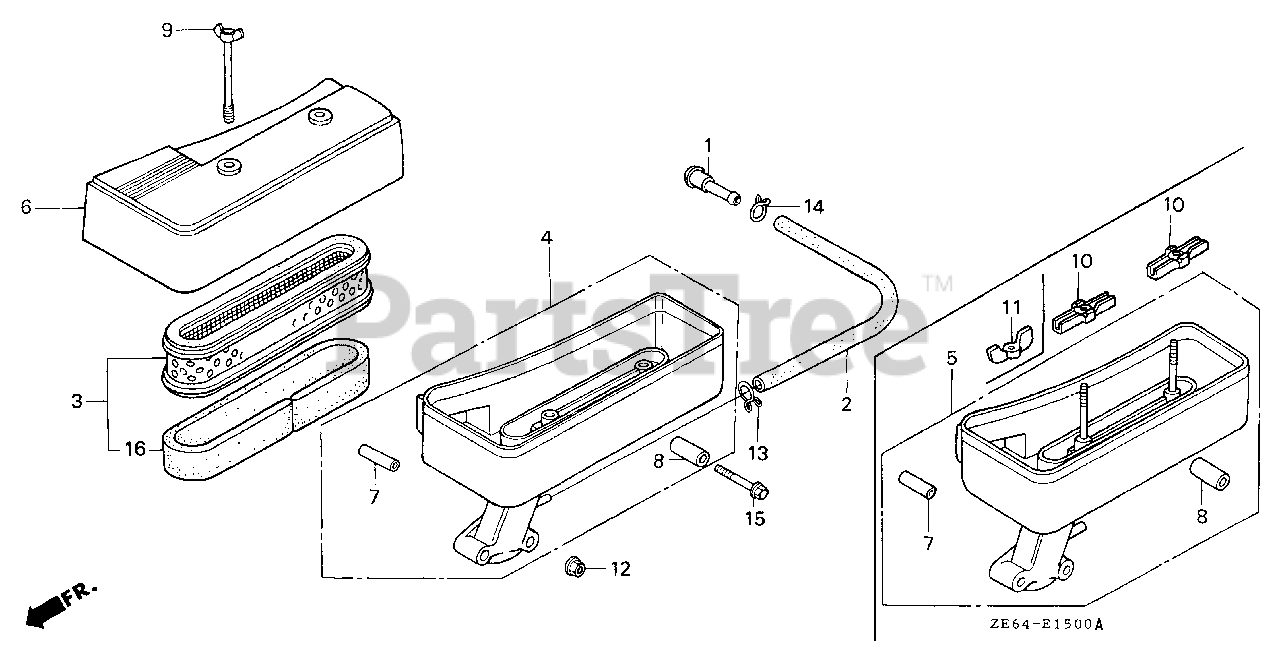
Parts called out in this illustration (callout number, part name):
2	TUBE, BREATHER
3	ELEMENT, AIR CLEANER
5	HOUSING, AIR CLEANER
6	COVER, AIR CLEANER
7	COLLAR, AIR CLEANER
8	COLLAR B, AIR CLEANER
11	WINGNUT, TOOL BOX SETTING
12	NUT, FLANGE (6MM)
14	CLIP, TUBE (C11)
15	BOLT, FLANGE (6X35)
